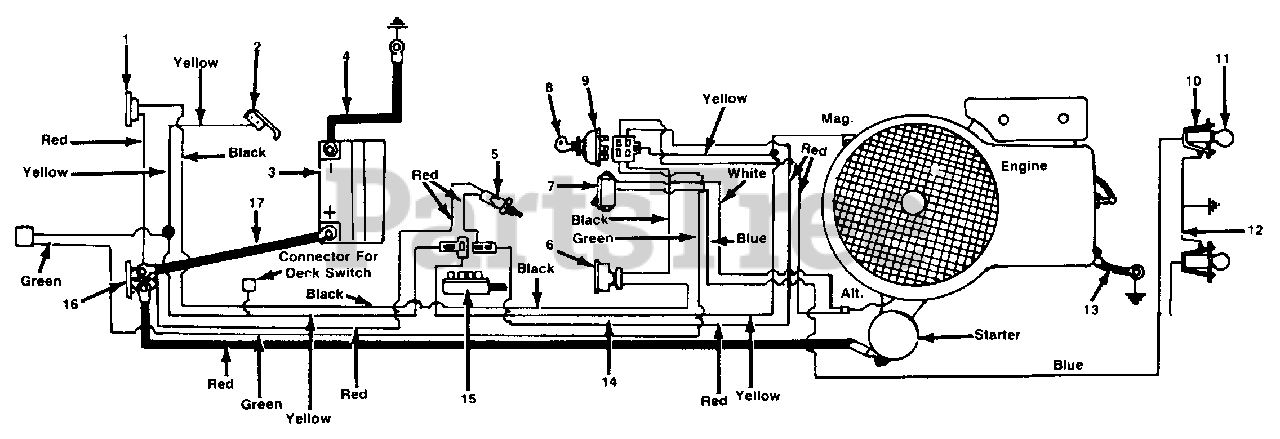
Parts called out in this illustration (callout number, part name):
1	Circuit Breaker
2	Spring Switch
3	12V Battery
4	Ground Wire 9.0" Lg.
5	Safety Switch
6	Ammeter
7	Light Switch
8	Ignition Key
9	Ignition Switch
10	Socket
11	Lamp
12	Grounding Wire
13	Ground Wire 7.25" Lg.
14	Wire Harness
15	Safety Switch
16	Solenoid
17	Electric Wire
